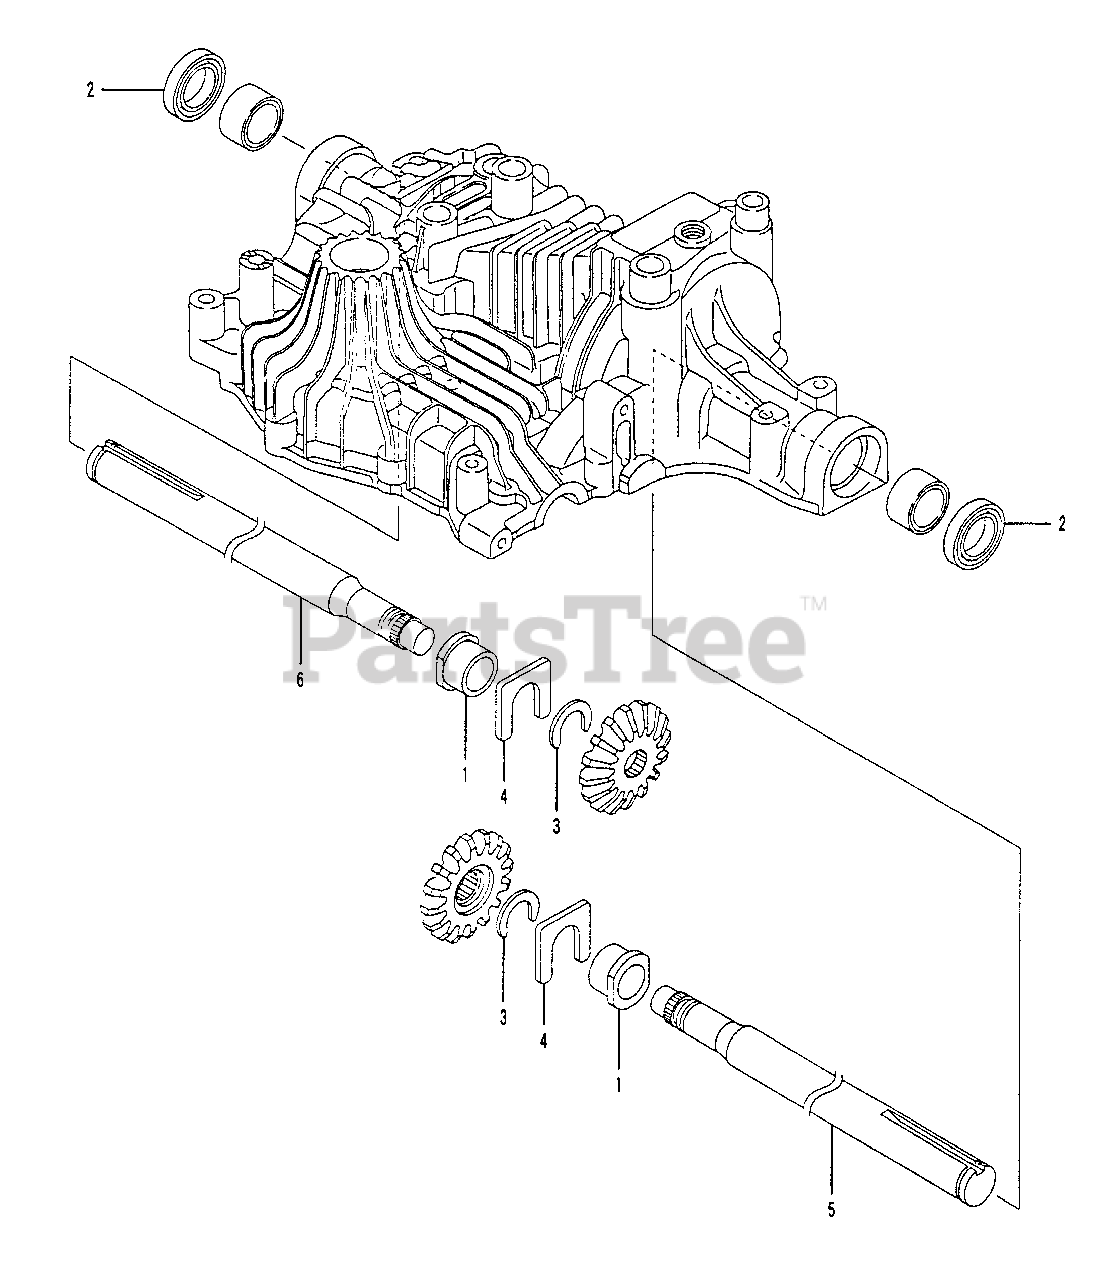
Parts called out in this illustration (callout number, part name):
2	SEAL (S25.4 X 42 X 8
4	THRUST WASHER
5	AXLE SHAFT L
6	AXLE SHAFT R
